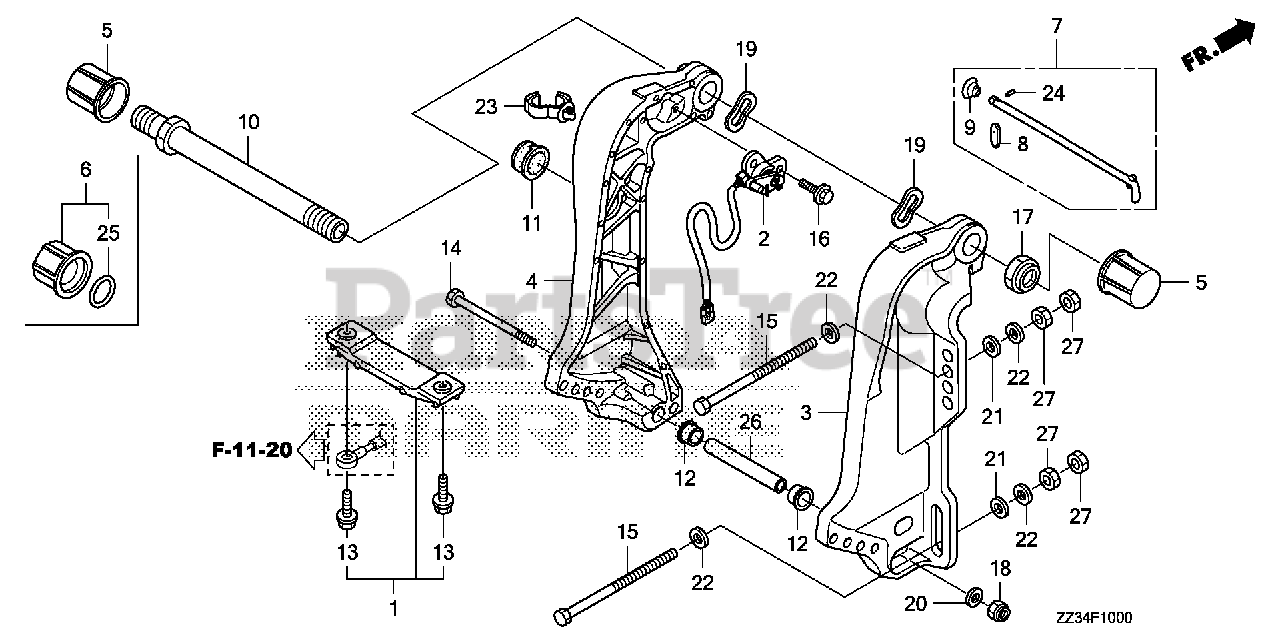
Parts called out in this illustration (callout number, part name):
1	METAL KIT, ANODE
2	SENSOR ASSY., TRIM ANGLE
3	BRACKET, R. STERN *NH282MU* (OYSTER SILVER METALLIC-U)
4	BRACKET, L. STERN *NH282MU* (OYSTER SILVER METALLIC-U)
7	ROD, ADJUSTING
8	STOPPER, ROD
9	SPRING, ADJUSTING ROD
10	SHAFT, TILT
11	BUSH, MOTOR CODE
12	BUSH, CYLINDER (LOWER)
13	BOLT, FLANGE (6X23)
14	BOLT, HEX. (10X158)
15	BOLT, HEX. (12X119)
16	BOLT, FLANGE (6X16) (SUS)
17	NUT, SELF-LOCK (7/8-14UNF)
18	NUT, FLANGE (10MM)
19	WASHER, WAVE (26MM)
20	WASHER, PLAIN (10MM)
21	WASHER, PLAIN (12MM)
22	WASHER, PLAIN (12MM)
23	CLIP, WIRE HARNESS
24	PIN, SPRING (2.5X8)
25	O-RING (15.54X2.62)
26	COLLAR, DISTANCE (10X90)
27	NUT, HEX. (12MM)
